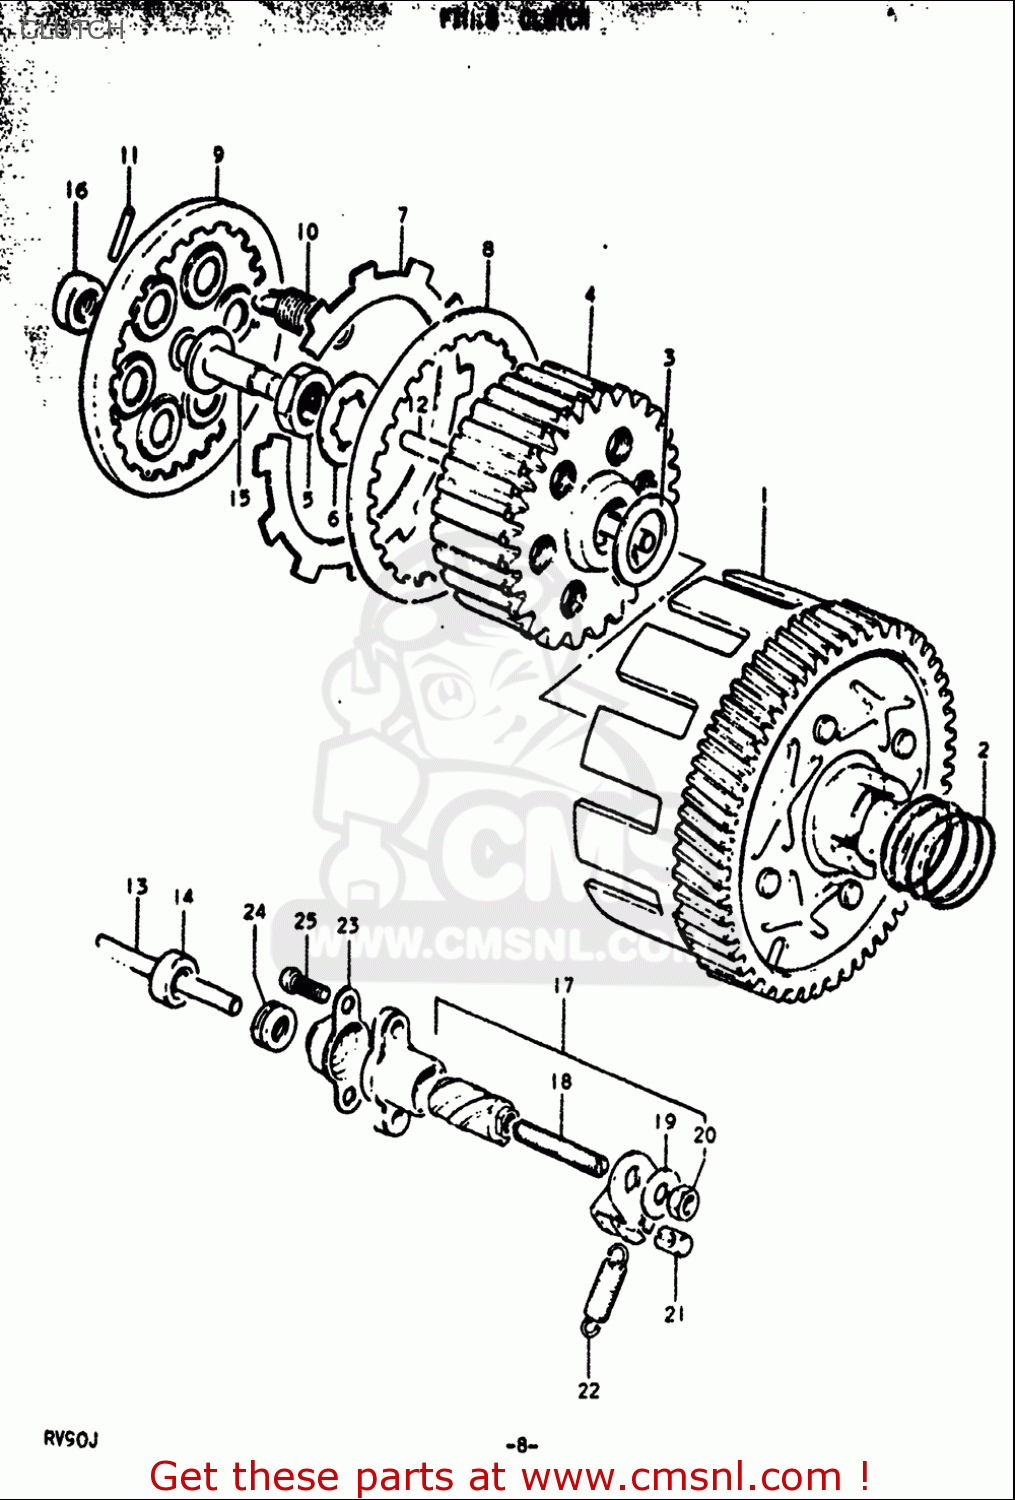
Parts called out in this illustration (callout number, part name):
2	SPRING
3	WASHER
4	HUB,CLUTCH SLEEVE
5	NUT
6	WASHER,LOCK
7	PLATE,CLUTCH DRIVE (NAS)
8	PLATE,CLUTCH DRIVEN (NAS)
9	PLATE,CLUTCH PRESSURE
10	SPRING
11	PIN(2.5X19.8)
12	ROD,CLUTCH PUSH
13	ROD,CLUTCH PUSH
14	SEAL,OIL(5.5X16X8)
15	ROD,CLUTCH RELEASE
16	SEAL,OIL (10X17X5)
17	SCREW ASSY,CLUTCH RELEASE
18	SCREW(6X25)
19	WASHER(6.5X16X1.2)
20	NUT
21	PIECE,RELEASE ARM END
22	SPRING
23	COVER,CLUTCH RELEASE SCREW
24	SEAL,DUST(5.3X13X5)
25	SCREW
